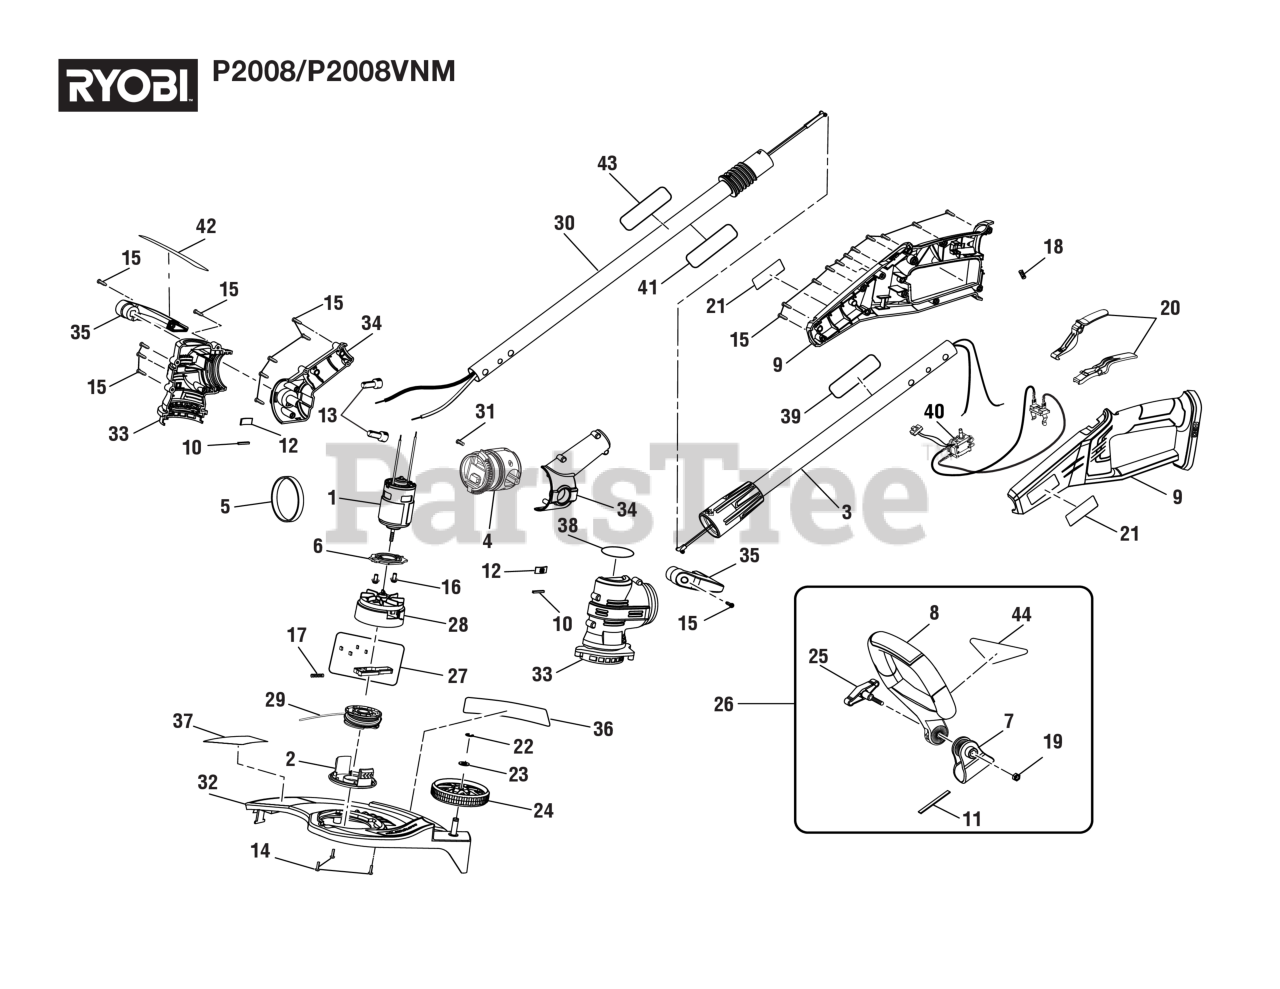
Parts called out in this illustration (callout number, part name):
3	Upper Tube and Wire Assembly
4	Pivot Assembly
5	Glamour Ring
6	Motor Mounting Plate
7	Handle Bracket
8	Front Handle
9	Handle Housing Assembly
10	Rubber Plate (Motor Plate)
11	Rubber Plate (Handle Bracket)
12	Rubber Plate (Motor)
13	Wire Connector (Closed End)
14	Screw (M4 x 12 mm, Pan Hd.)
15	Screw (M4 x 14 mm, T15 Torx Pan Hd.))
16	Screw w/Lock Washer (M5 x 8 mm, Pan Hd.)
17	Compression Spring (Internal Tooth)
18	Compression Spring (Trigger)
19	Lock Nut (M6)
20	Switch Trigger and Lock-Out Assembly
21	Logo Label (Upper End)
23	Washer (OD16 x ID8.2 x 1.2t)
25	Knob Bolt (M6 x 1 in.)
26	Auxiliary Handle Assembly
27	Slider Assembly
28	Spool Base w/Fan
30	Lower Tube Assembly
31	Screw (M3 x 12 mm, Pan Hd.)
32	Guard Assembly
33	Motor Housing Assembly
34	Lower Housing Assembly
35	Adjustment Pedal Assembly
36	Auto Feed No Bump Label (Guard)
37	Adjustable Cutting Width Label
38	Motor Housing Label
39	Data Label
40	Switch and Contact Plate Assembly
41	Warning Translation Label
42	Step For Edging Label
43	Warning Icon Label
44	Auto Feed No Bump Label (Handle)
